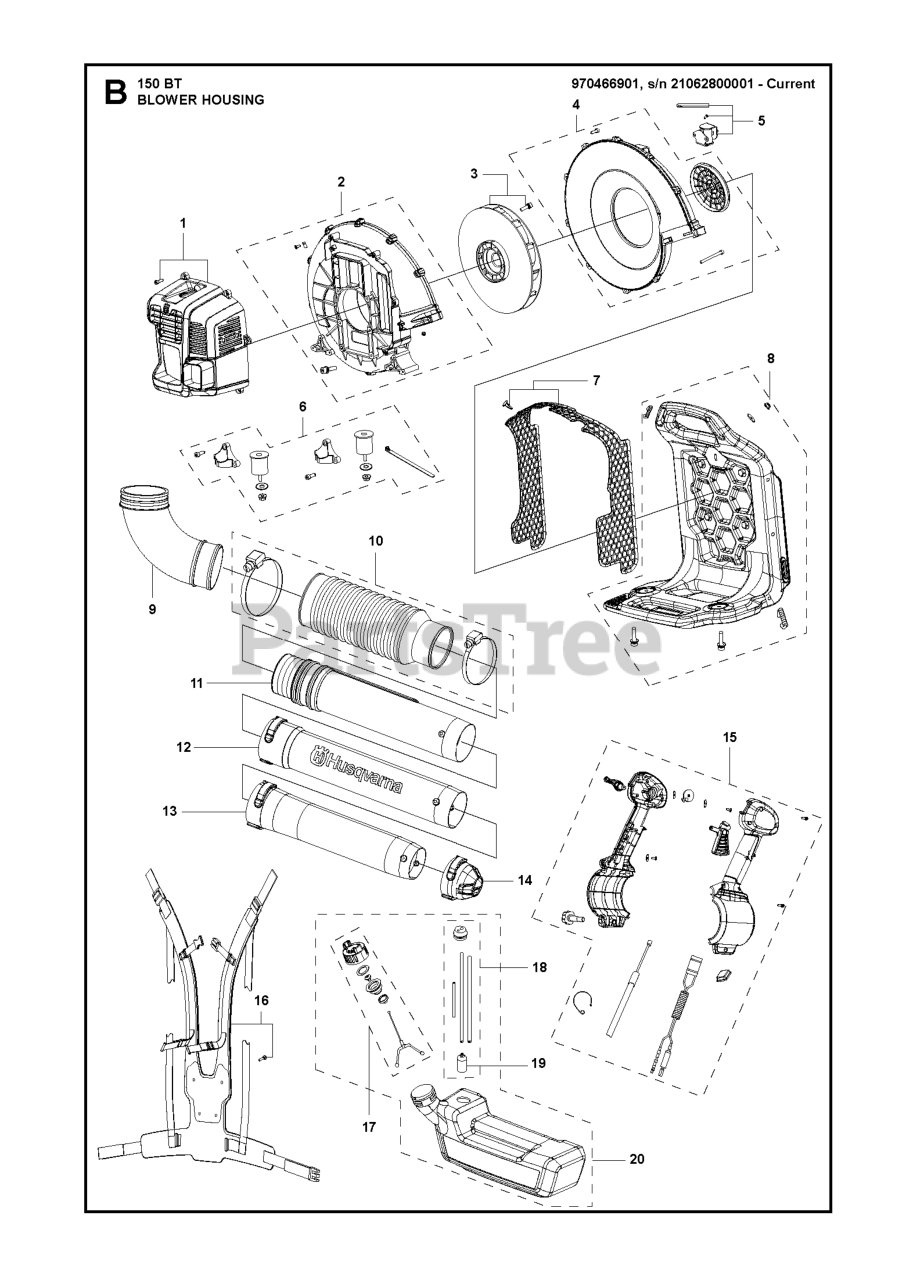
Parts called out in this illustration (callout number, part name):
6	REPAIR KIT DAMPER - LOWER
10	REPAIR KIT HOSE ASSY
19	FUEL FILTER
